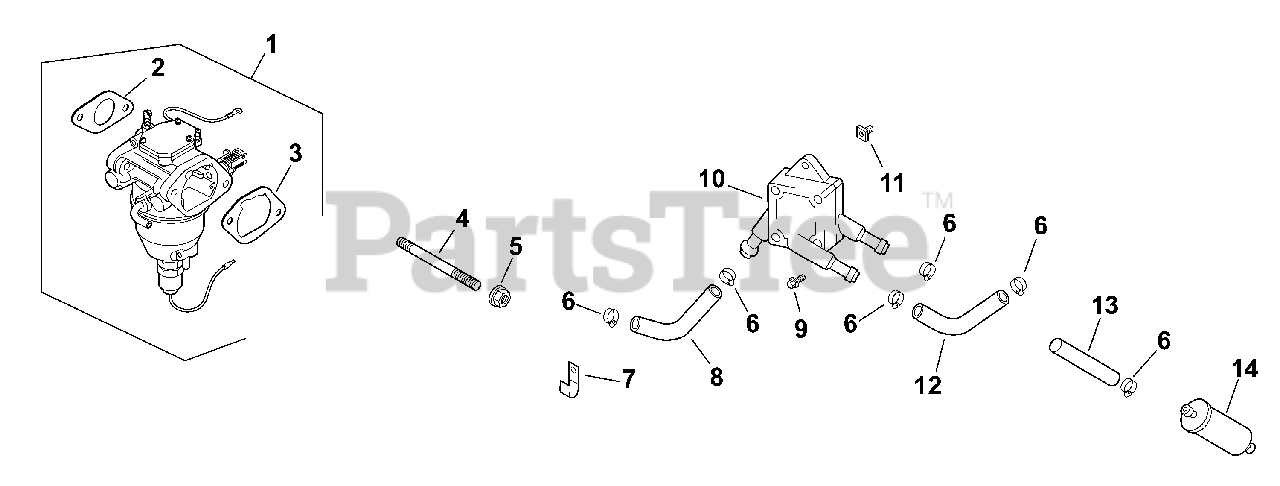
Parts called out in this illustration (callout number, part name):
1	CARBURETOR KIT-USE 24 853 169-S
2	GASKET, CARBURETOR
3	GASKET, AIR CLEANER BASE
4	STUD,M6X1.0X96
5	NUT, FLG M6X1.0
6	CLAMP, HOSE (KM)-USE 25 237 31-S
7	CLIP, CABLE
8	LINE, FLEXIBLE FUEL 12.3"-USE 25 111 81-
9	SCREW, TAP M6X1.7X18
10	PUMP, FUEL
11	NUT, PLASTIC (KM)-USE 25 100 37-S
12	LINE, FLEXIBLE FUEL 10.92"-USE 24 353 12
13	LINE - (#DSC)
